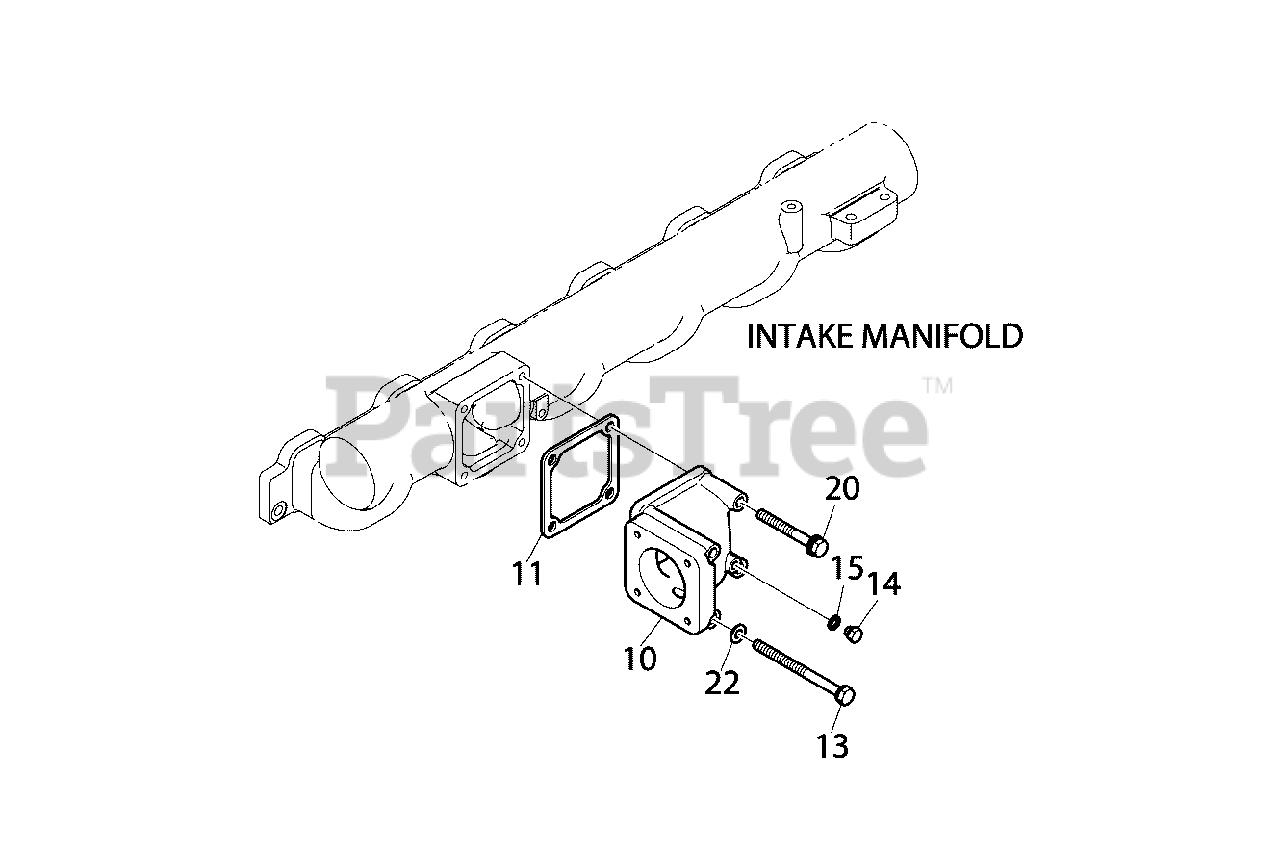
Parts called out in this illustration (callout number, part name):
10	* INTAKE STAKE
11	GASKET
13	* BOLT
14	* PLUG
15	* SEAL
20	* BOLT
22	* WASHER
